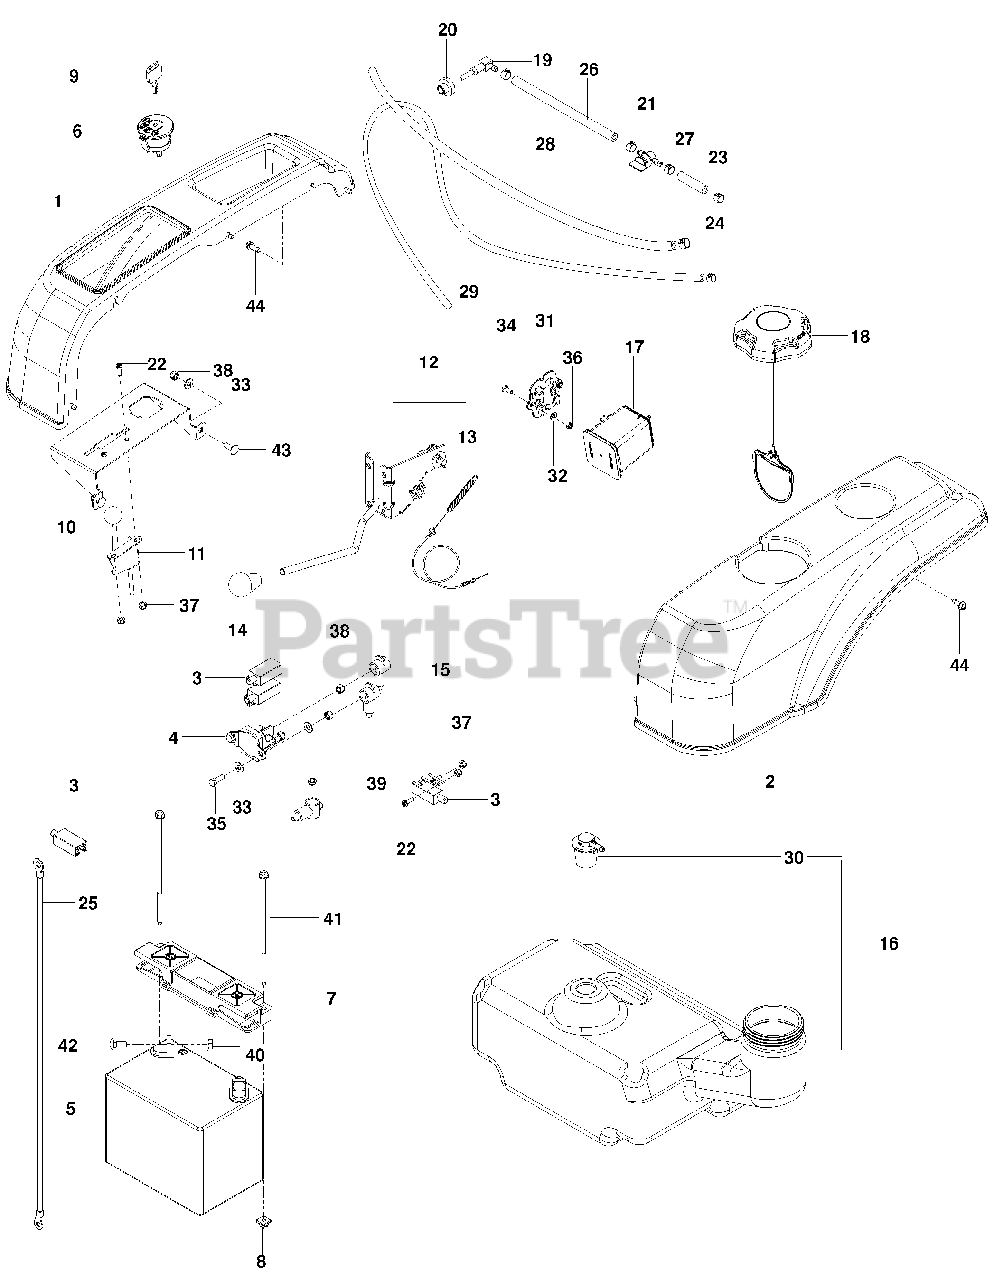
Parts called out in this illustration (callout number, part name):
1	FENDER, RH
2	FENDER, LH
5	BATTERY
6	SWITCH, IGNITION
7	BATTERY HOLD DOWN
8	NUT 1/4 PUSH NYLON
9	KEY, IGNITION
10	MOUNT, CONTROLS BLK
11	CABLE, THROTTLE
12	CLUTCH ASSY w/ CABLE
13	CABLE, CLUTCH
14	KNOB, CLUTCH
15	TERMINAL COVER, SM
16	TANK, FUEL w/ VALVE
17	CANISTER, CARBON
18	CAP, FUEL w/ TETHER
19	ELBOW w/ FILTER
20	FITTING, TANK
21	VALVE, FUEL
22	SCREW #10-24 x 5/8
23	CLAMP, HOSE
24	CLAMP, HOSE
25	BATTERY CABLE, NEGATIVE
26	HOSE 1/4 x 8
27	HOSE, 1/4 x 2
28	FUEL LINE 24"
29	FUEL LINE 46"
30	VALVE, ROLLOVER
31	BRACKET, CANISTER
32	WASHER 5/16 SAE FLAT
33	WASHER 1/4 FLAT SAE
34	HCS 5/16-18 x 5/8
35	HCS 1/4-20 x 3/4
36	NUT 5/16-18 HEX NYL INSERT
37	NUT #10-24 HEX NYLOC
38	NUT 1/4-20 HEX NYLOC
39	NUT 1/4-20 HEX THIN NYLOC
40	NUT 5/16-18 FLANGE NYLOC
41	BOLT 1/4 x 7 1/2
42	RHSNB 5/16-18 x 3/4
43	RHSNB 1/4-20 x 3/4 GR2
44	SCREW 1/4-20 x 5/8 SLF TAP
